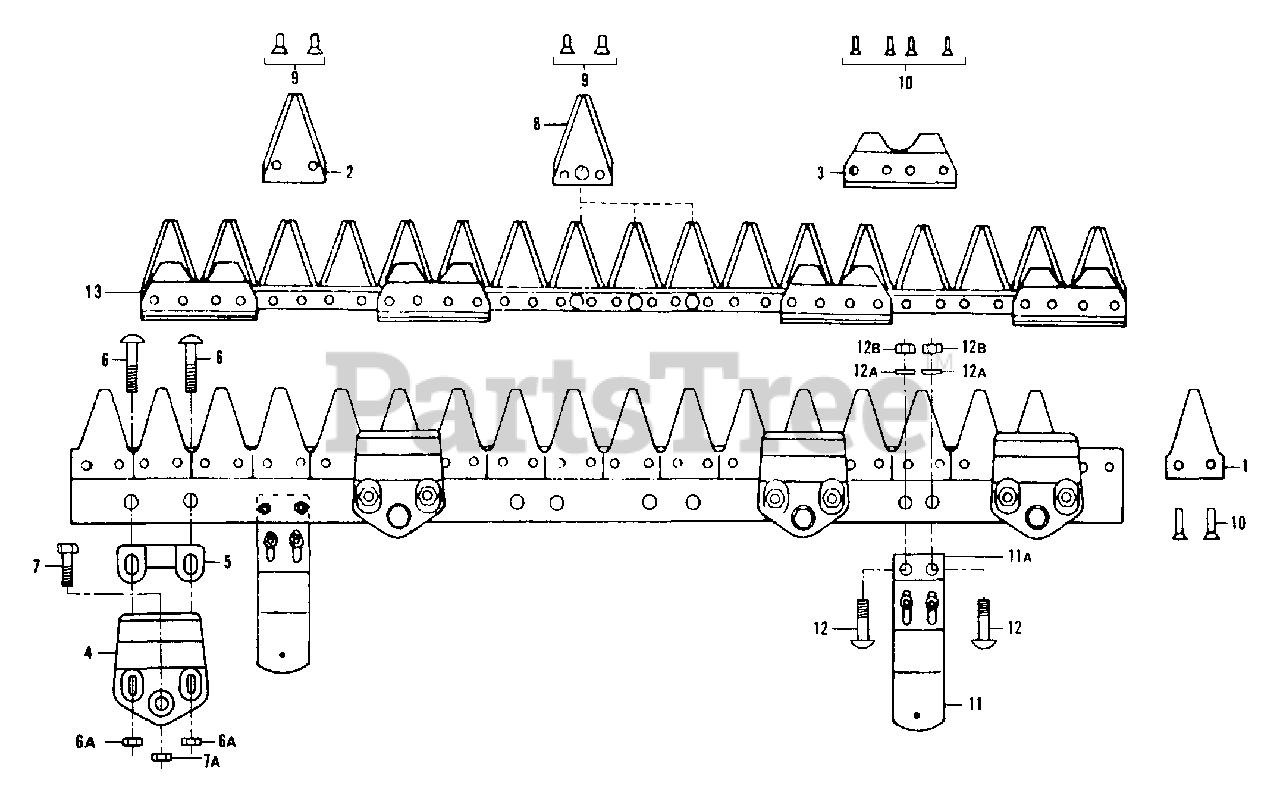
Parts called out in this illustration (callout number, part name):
1	Blade Section
2	Blade Section-2 Holes
4	Blade Guide
6	Bolt M8 x 40
6A	Nut
7	Bolt HHM8 x 30
7A	Nylon Nut
8	Blade Section-3 Holes
9	Rivets CS90 5.3 x 14
10	Rivets CS90 5.3 x 16
11	Height Adjuster (Rear Half)
11A	Height Adjuster (Forward Half)
12	Bolt M8 x 25
12A	Washer
13	Complete Cutter Blade Assembly
